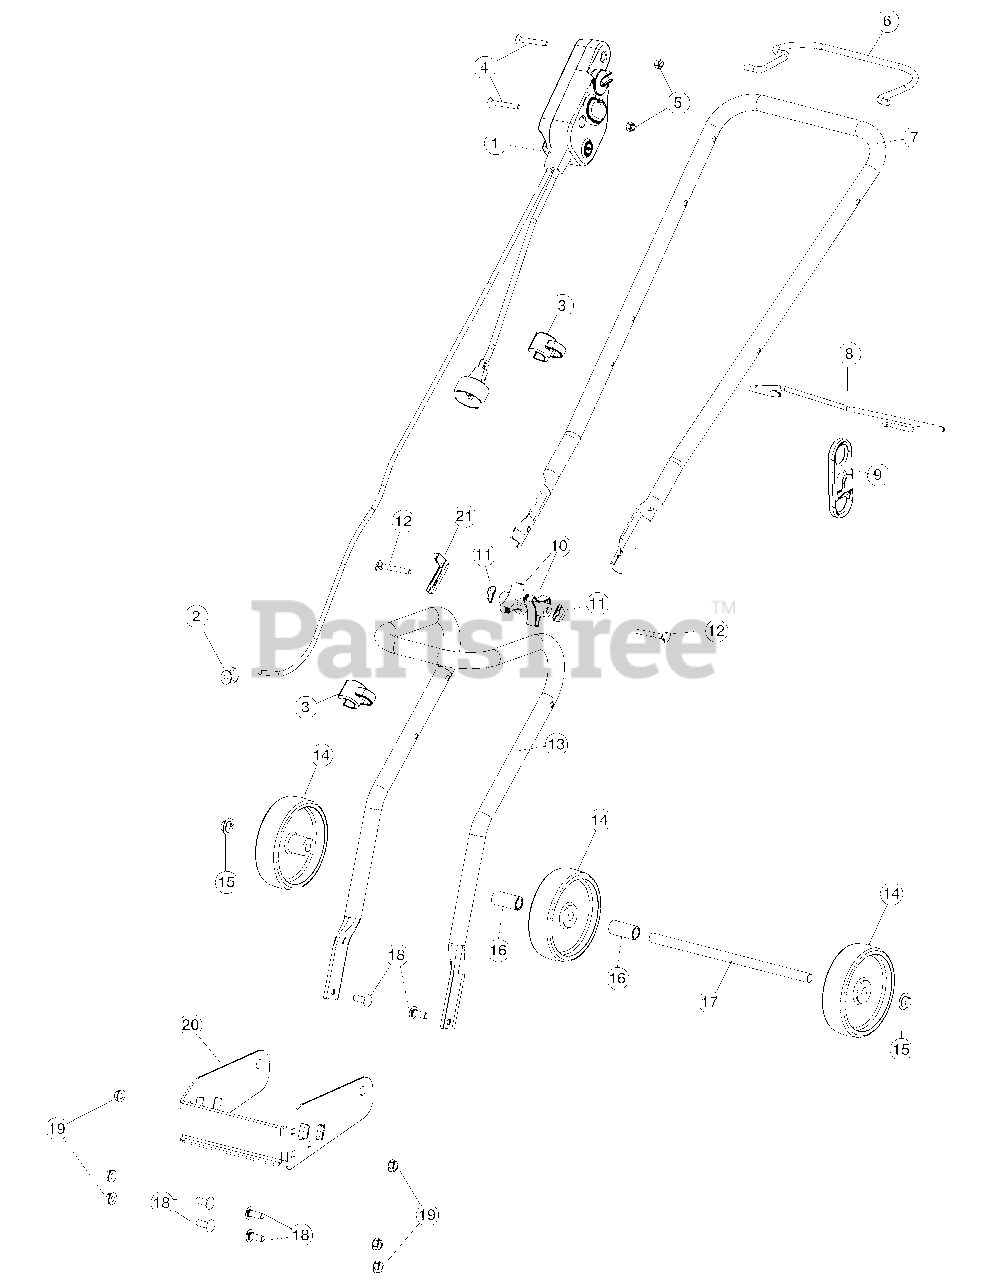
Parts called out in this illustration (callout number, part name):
1	Switch Asm
2	Bushing
3	Cable guide
5	Nut
7	Upper Handle
8	Guide Bar
9	Cord Restraint
11	Washer
13	Lower Handle
15	Push Cap
16	Spacer
18	Bolt
19	Nut
20	Wheel Bracket
21	Control Rod Bracket
